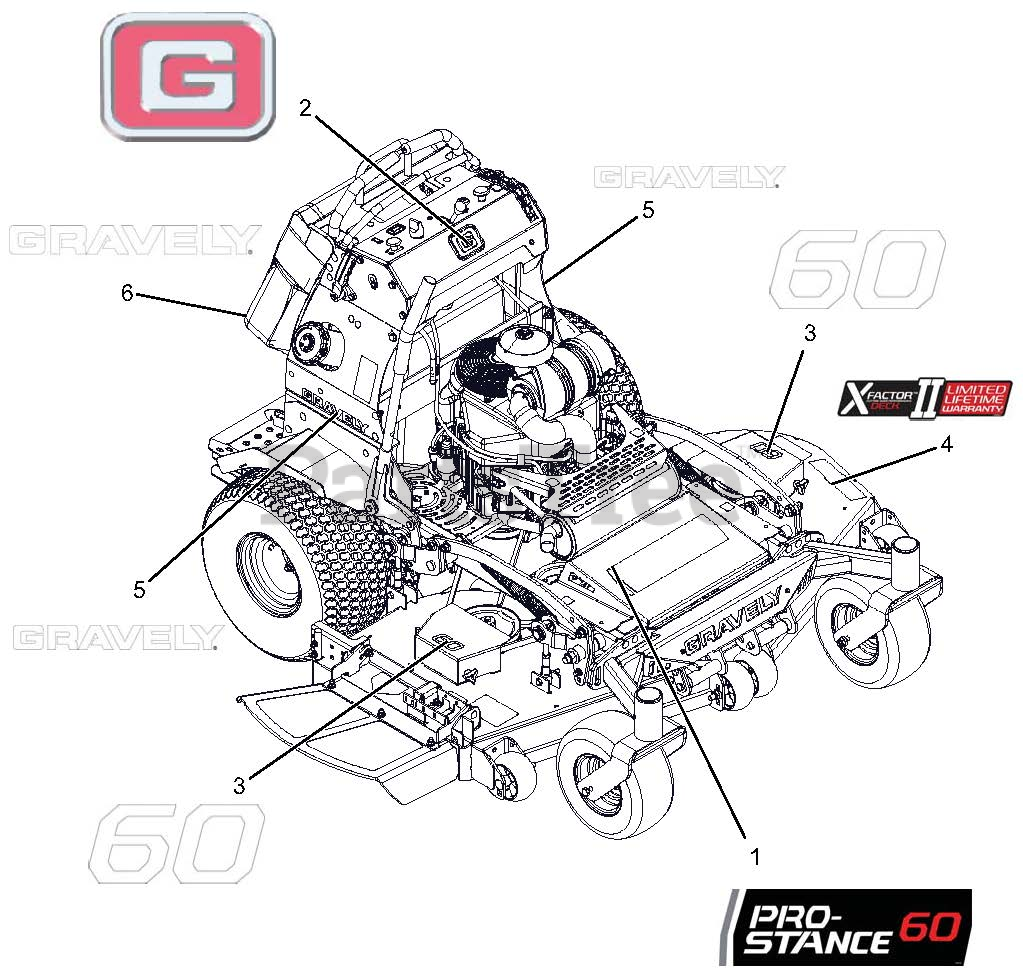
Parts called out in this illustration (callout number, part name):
1	DECAL, PROSTANCE 60
2	DECAL, GRAVELY BRAND
3	DECAL, 60"
4	DECAL, X-FACTOR DECK
5	DECAL, 9.5" GRAVELY LOGO
6	DECAL, 13.5" GRAVELY LOGO
